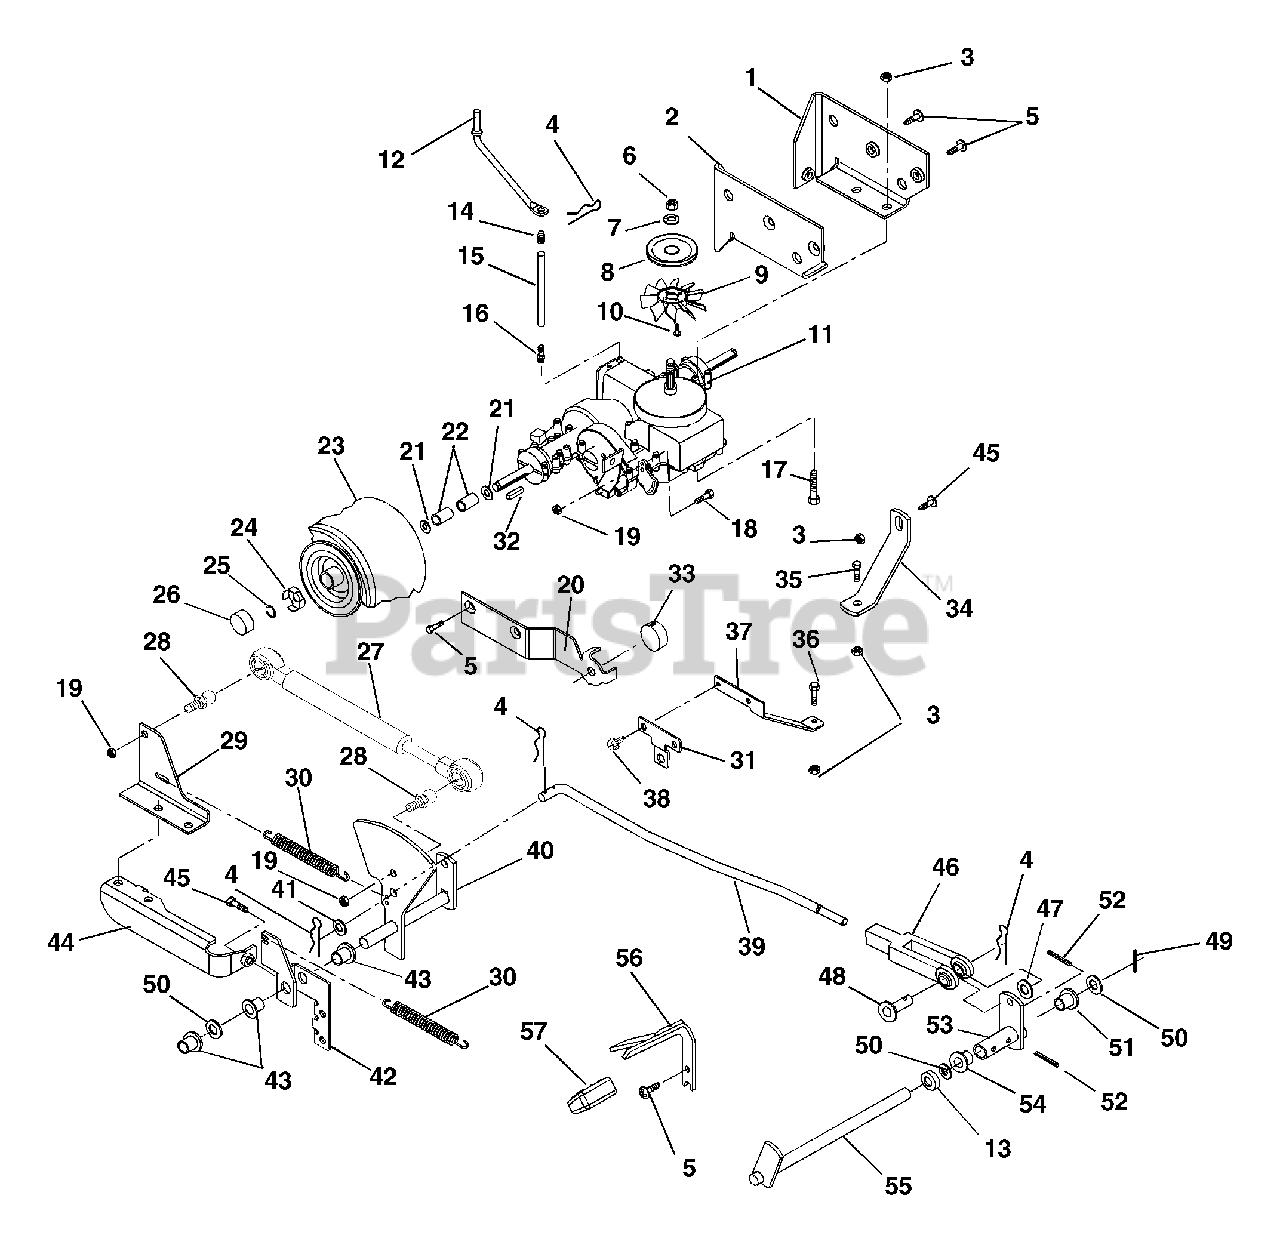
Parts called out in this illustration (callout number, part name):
1	TRANS MOUNT, LH
2	TRANS MOUNT, RH
3	@NUT-LK-TOP-FLG .31-18 YWZC
4	PIN-HAIR INT .08X.18X1.18 YWZC
5	@SCR-TAP .38-16X1.00 HWH TR YZ
6	NUT-JAM .50-20 GR2 YWZC
7	@WSHR-LK .50X.125 REG YWZC
8	SHEAVE - TRANSAXLE
10	SCR-TAP 10-24X.484 HWH TR
11	TRANSAXLE- HYDRO #325-0750
12	ROD, TRANS DISCONNECT
13	BSHG, SPCR.500X.750X.321 PM
14	CAP-VENT .50
15	HOSE- VENT .50ID X 7.50LONG
16	FTG-STR .50 O-RING
17	@BLT-HEX .31-18X2.50 GR5 YWZC
18	@BLT-HEX .31-18X.75 GR5 YWZC
19	@NUT-LK-CTR .31-18 YWZC
20	MOUNT, MAGNET
21	WSHR-FL-STL.755X1.375X.062YWZC
22	SPACER, WHEEL (YT 2548)
23	ASSEMBLY, 22 INCH TIRE/WHEEL
23	RIM, 22 IN TIRE
23	T/WHL ASSY 18X8.50-8
24	SPINDLE CUP
25	RG-RTNG-EXT .750X.050
26	HUB CAP
27	DAMPER - HYDRAULIC
28	STUD- BALL
29	ANCHOR - SPRING - TOP
30	SG-TENS .085X.60X5.13 WLD8.3
31	SUPPORT, SHIFT ARM
32	KEY-SQ .188X2.0X.188 SAE 8630
34	STRAP, TORQUE L.H (HYDRO)
35	@BLT-HEX .31-18X1.50 GR5 YWZC
36	@BLT-HEX .31-18X2.25 GR5 YWZC
37	STRAP, TORQUE R.H (HYDRO)
38	SCR-TAP .312-18X.50 HWH TR BL
39	ROD, SHIFT
40	ARM, SHIFT (WELDMENT)
41	@WSHR-FL-STL.406X.812X.065 YWZ
42	PIVOT - REVERSE
43	BSHG-FLG .508X.645X.459X.75 NY
44	ANCHOR - SPRING - BOTTOM
45	@BLT-HEX .31-18X.75 GR5 YWZC
46	YOKE, .312-24 X 2.25
47	WSHR-FL-STL .390X.75X.125 YWZC
48	PIN-CLEV .312X.822 HDND PL
49	@PIN-CTR .12X1.00 EXTPRSQCT YZ
50	WSHR-FL-STL .52X.827X.062 YWZC
51	BSHG-FLG .515X.750X.745X1.00NY
52	PIN-GRV .188X1.25 TP A
53	ARM & HUB
54	BSHG-FLG .502X1X.750
55	SHAFT-PEDAL (SINGLE)
56	PEDAL-F/R SIERRA COMP
57	COVER - PEDAL - FORWARD
